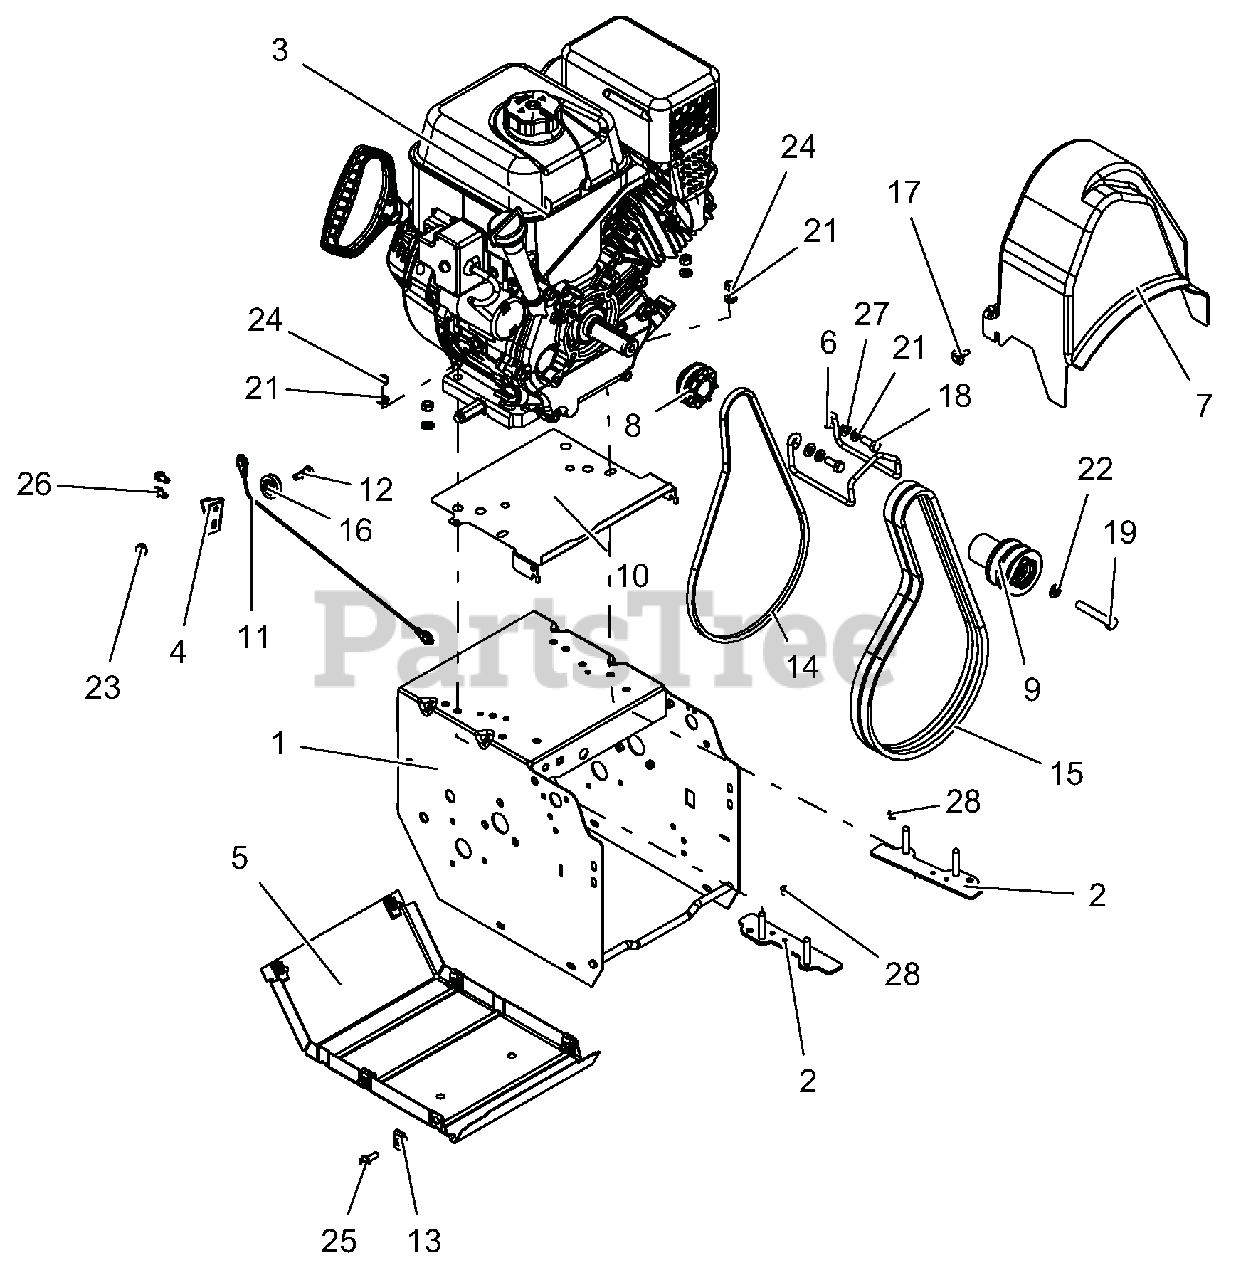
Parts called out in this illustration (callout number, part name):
1	WELDMENT, FRAME - DELUXE 16"
2	STRAP,ENGINE BOLT,ARIENS MED
3	ENGINE, ARIENS AX291 240V/60W
4	BRACKET, CABLE PULLEY
5	COVER, BOTTOM
6	FINGER, BELT
7	BELT COVER
8	SHEAVE, DRIVE
9	SHEAVE,ATTACHMENT 2-GRV
10	BAFFLE,ENGINE,ARIENS MED BLOCK
11	CABLE, LOWER TRACTION (DELUXE)
12	BOLT, SHLDR-.375X.375X.25-20
13	NUT-RTNR .25-20X.56
14	V-BELT, 3L-WRAPPED
15	V-BELT, HA-RAW EDGE (SET)
16	PULLEY, CABLE
17	SCR-TAP .25-20X.5 CAPTIVE
18	BLT-HEX .31-24X.75 YWZC GR5
19	BLT-HEX .38-24X2.25 YWZC GR5
21	WSHR-LK .312X.097 HVY YWZC
22	@WSHR-LK .38X.094 REG YWZC
23	@NUT-LK-CTR-FLG .25-20 YWZC
24	@NUT-HEX .31-18 YWZC
25	BLT-HEX .25-20X.75 HWH YZ GR5
26	SCR-TAP .25-20X.50 HWH TR YWZ
27	@WSHR-FL-STL.344X.688X.065YWZC
28	RVT-POP .187 YZ
